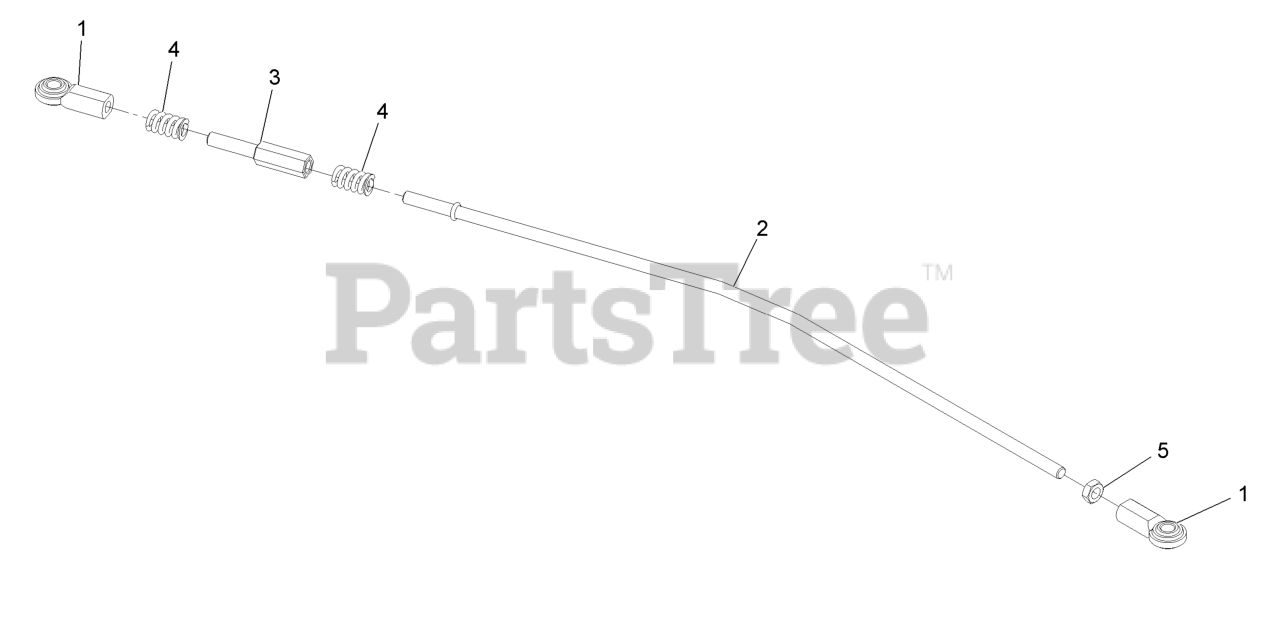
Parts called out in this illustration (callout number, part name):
1	JOINT-BALL, END
2	LINK-LOWER, MOTION CONTRO
3	ROD-ADJUSTMENT
4	SPRING, COMPRESSION
5	NUT-HJ
